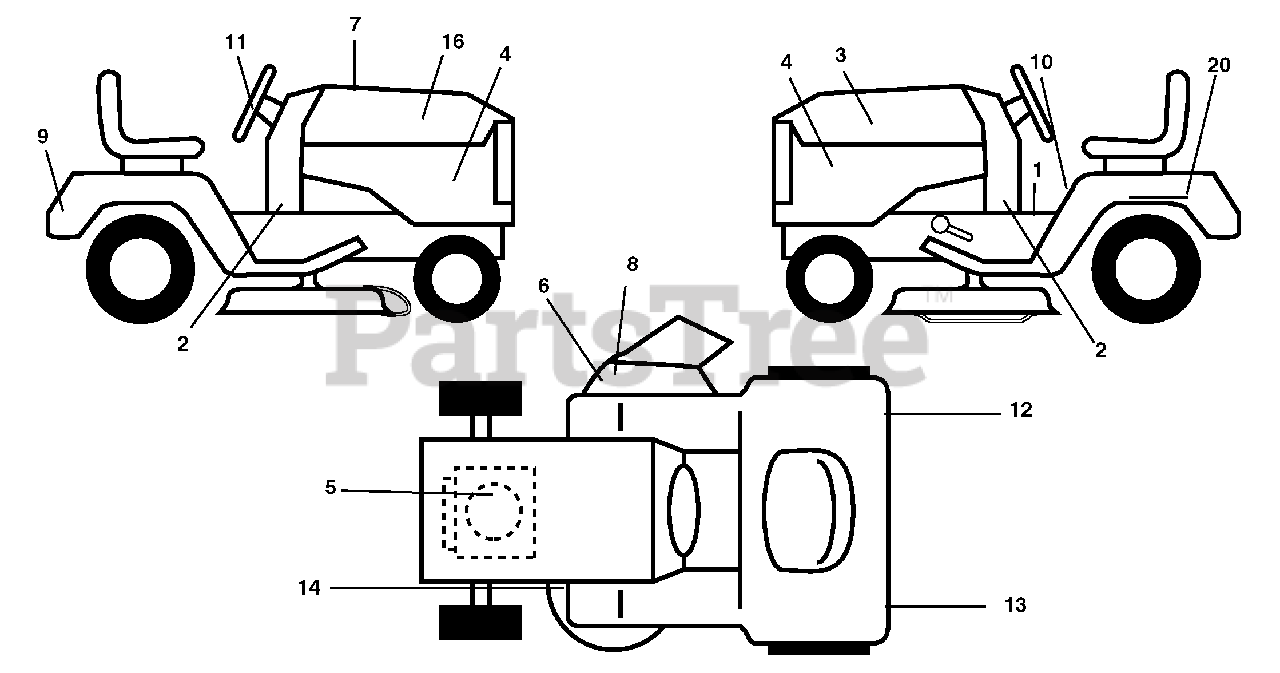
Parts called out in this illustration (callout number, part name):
1	Decal, Oper
2	Decal, Lower Dash
3	Decal, Hood LH
4	Decal, Side Panel Logo
5	Decal, HP Engine
6	Decal, Warning, Keep Hand Away
7	Decal, Replacement Parts
8	Decal, Deck "B" 42"
9	Decal, Fender Logo
10	Decal, Fender Danger E/F
11	Decal, Ins Strg Whl
12	Decal, Fend Reflector Rh
13	Decal, Fend Reflector Lh
14	Decal, V-Belt Schematic
16	Decal, Hood Rh
20	Decal, Bat Dan/Psn
20	Pad Footrest LH
20	Pad Footrest RH
20	Decal, Bypass
20	Decal, Chass Disconnect
20	Decal, Handle Lft Height Adjust
20	Manual Operator's E&F
20	Manual Parts
